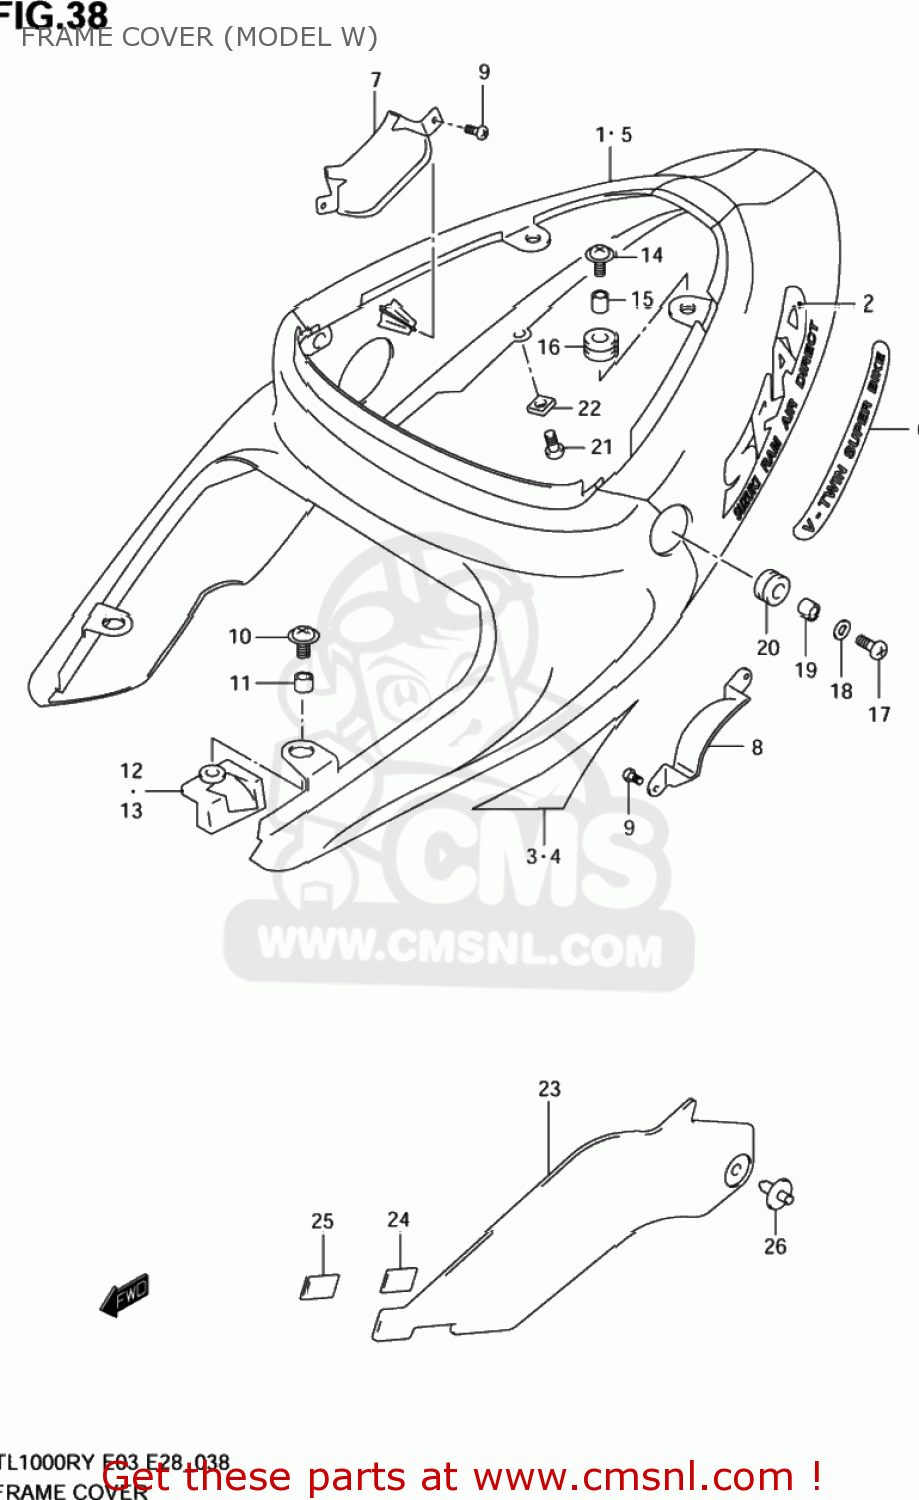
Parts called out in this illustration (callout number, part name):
1	COVER,FRAME,RIGHT
2	EMBLEM,FRAME COVER
3	TAPE,FRAME COVER,R(BLUE)
4	TAPE,FRAME COVER,L(BLUE)
5	COVER,FRAME
6	EMBLEM,FRAME COVER
7	CAP,FRAME COVER HOLE,R
8	CAP,FRAME COVER HOLE,L
9	SCREW
10	SCREW(6X20)
11	SPACER(6.5X9X9)
12	CUSHION,FRAME COVER,R
13	CUSHION,FRAME COVER,L
14	SCREW(6X20)
15	SPACER(6.5X10X9.4)
16	CUSHION
17	SCREW(6X20)
18	WASHER(6.5X22X1.6)
19	SPACER(6.5X9X6.7)
20	CUSHION
21	SCREW
22	NUT
23	COVER,FRAME,FRONT,RIGHT
24	FASTENER,NO.1
25	FASTENER,NO.2
26	CLIP(GRAY)
